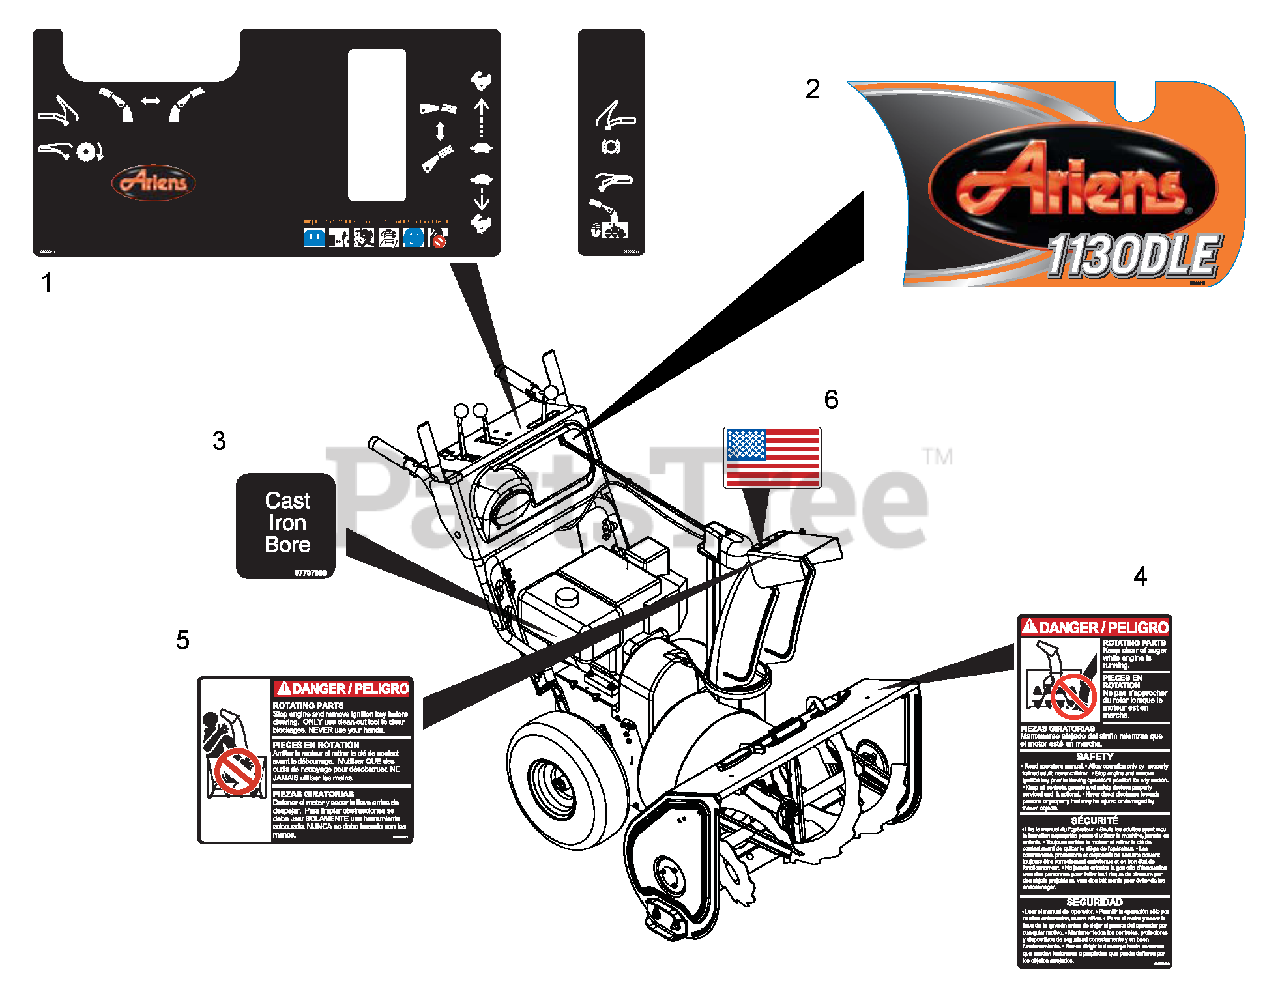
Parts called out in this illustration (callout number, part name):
1	DECAL, CONTROL
2	DECAL,ST924DLE CLASSIC
3	DECAL - CAST IRON BORE
4	DECAL, DANGER
5	DECAL, DANGER - ROT. PARTS
6	DECAL, AMERICAN FLAG
